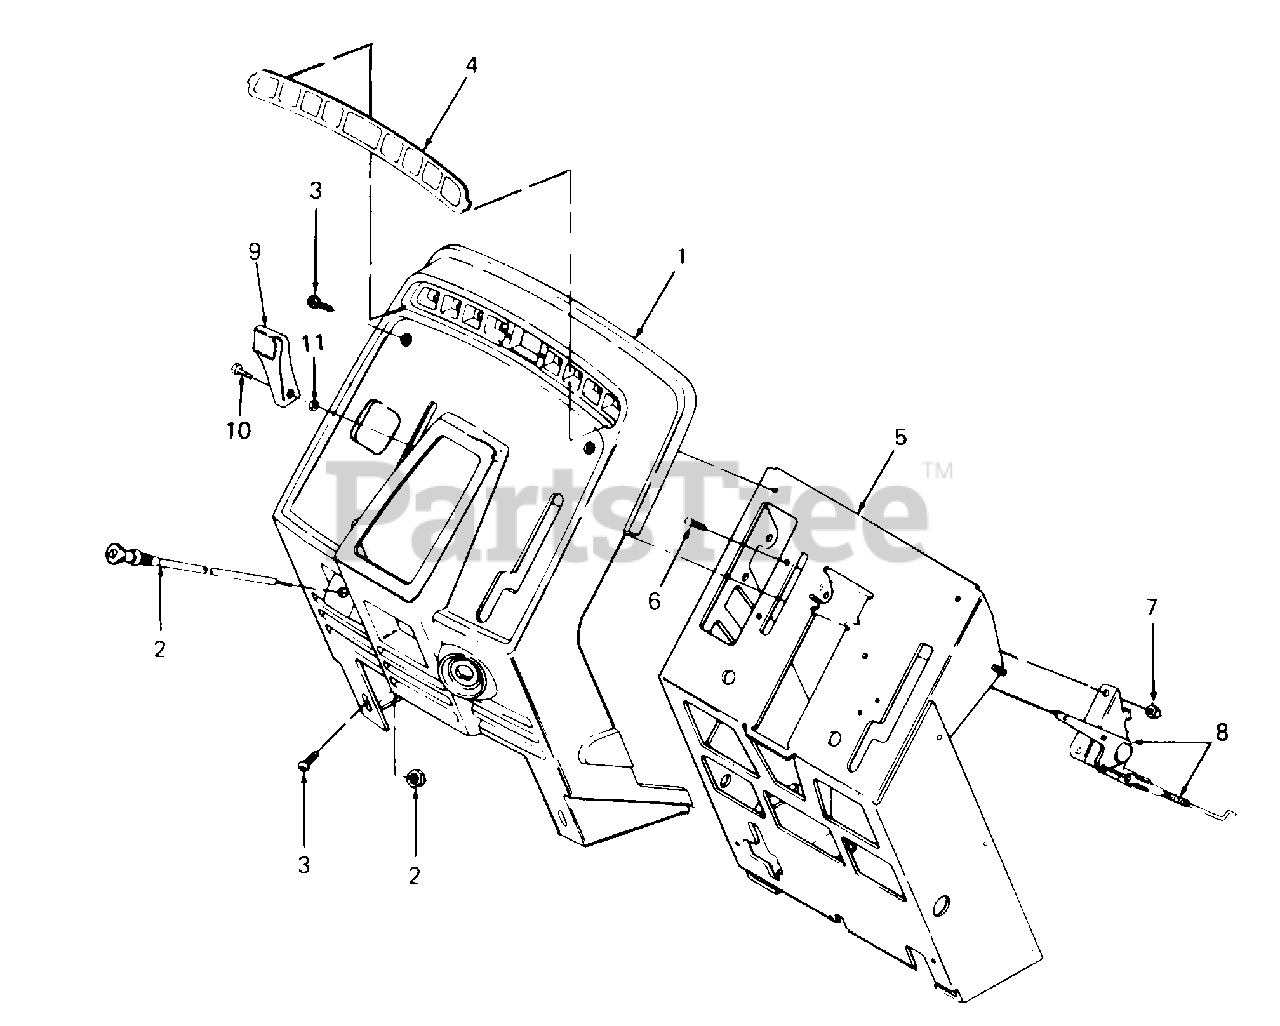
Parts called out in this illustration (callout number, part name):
1	Panel, Instrument
2	Choke Cable w/Nut
3	Screw, Pan Hd Cutting, #10-24 X .75 Lg
4	Label, Dash
7	Nut, Hex Keps, #10-32
8	Control, Throttle
9	Knob, Throttle
10	Screw, Cross Rec Truss Hd, #8-32 X .38 Lg
11	Nut, 8-32
